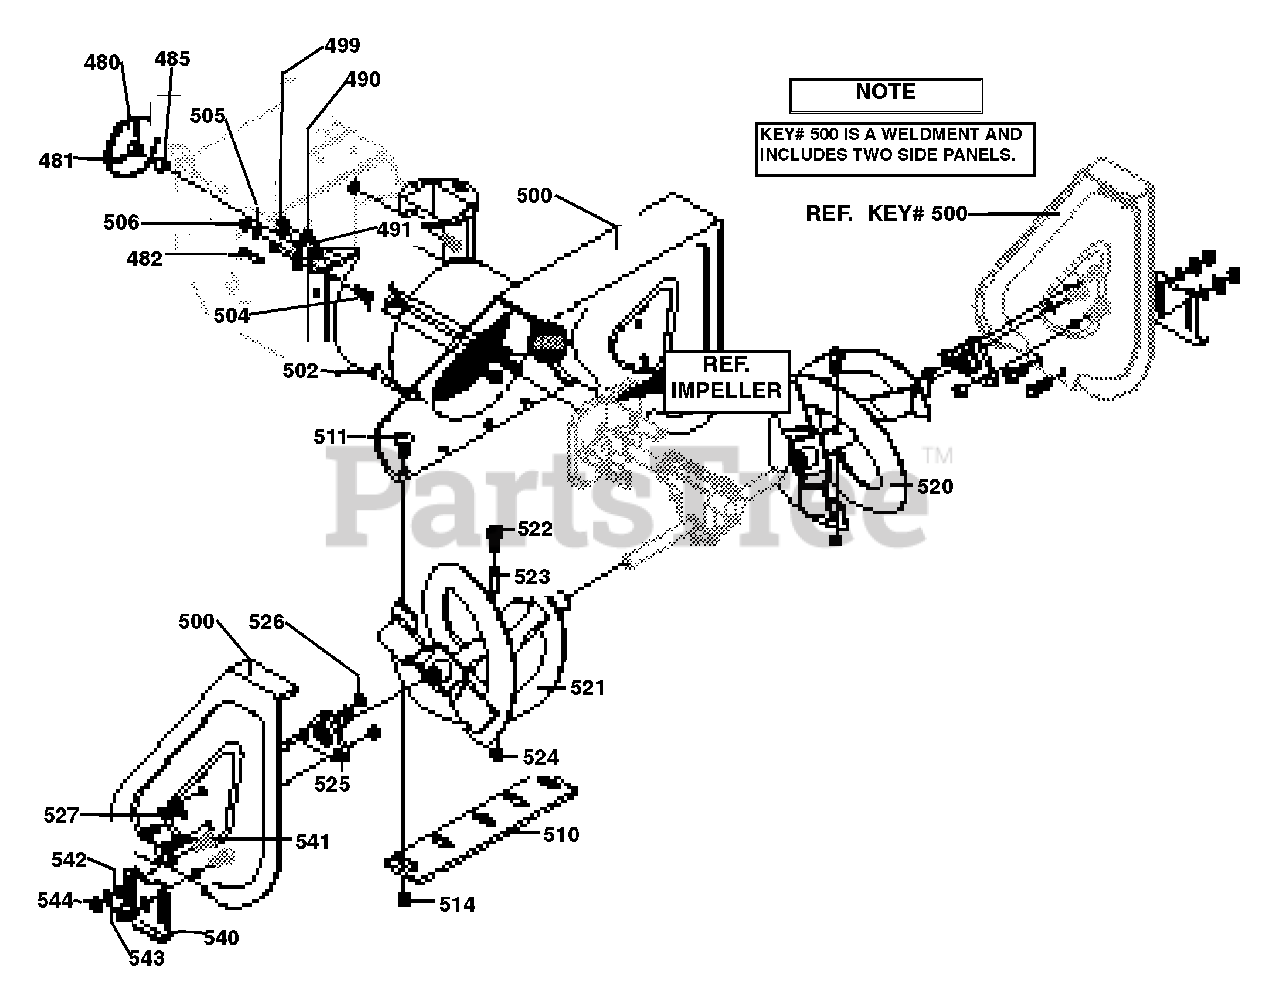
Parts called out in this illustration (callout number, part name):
480	PULLEY, V4L
481	SCREW, 5/16-18 X .63
482	KEY, SQUARE
485	SPACER, SLEEVE
490	RETAINER, BALL
491	BEARING, BALL
493	SCREW, 5/16-18 X .75
499	NUT, 5/16-18
500	HOUSING, ASSY
502	RATCHET FASTENER
504	SCREW, 3/8-16 X .75 HHC
505	WASHER, REGSPTLK
506	NUT, 3/8-16
510	SCRAPER BLADE
511	BOLT, 1/4-20 X .75 CARR.
514	NUT, 1/4-20
520	AUGER, ASSY LH
521	AUGER, ASSY RH
522	SCREW, 1/4-20 X 1.75
523	SPACER, SLEEVE
524	NUT, 1/4-20 REGHXCTRLK
525	FLANGE BEARING
526	NUT, 5/16-18 HXWDFLLK
527	SCREW, 5/16-18 X .75
540	SKID, HEIGHT ADJUST
541	BOLT, 5/16-18 X .75
542	FLATWASHER .344 X .69 X .065
543	WASHER, .328 X .60 X .09
544	NUT, 5/16-18 REGHEX
